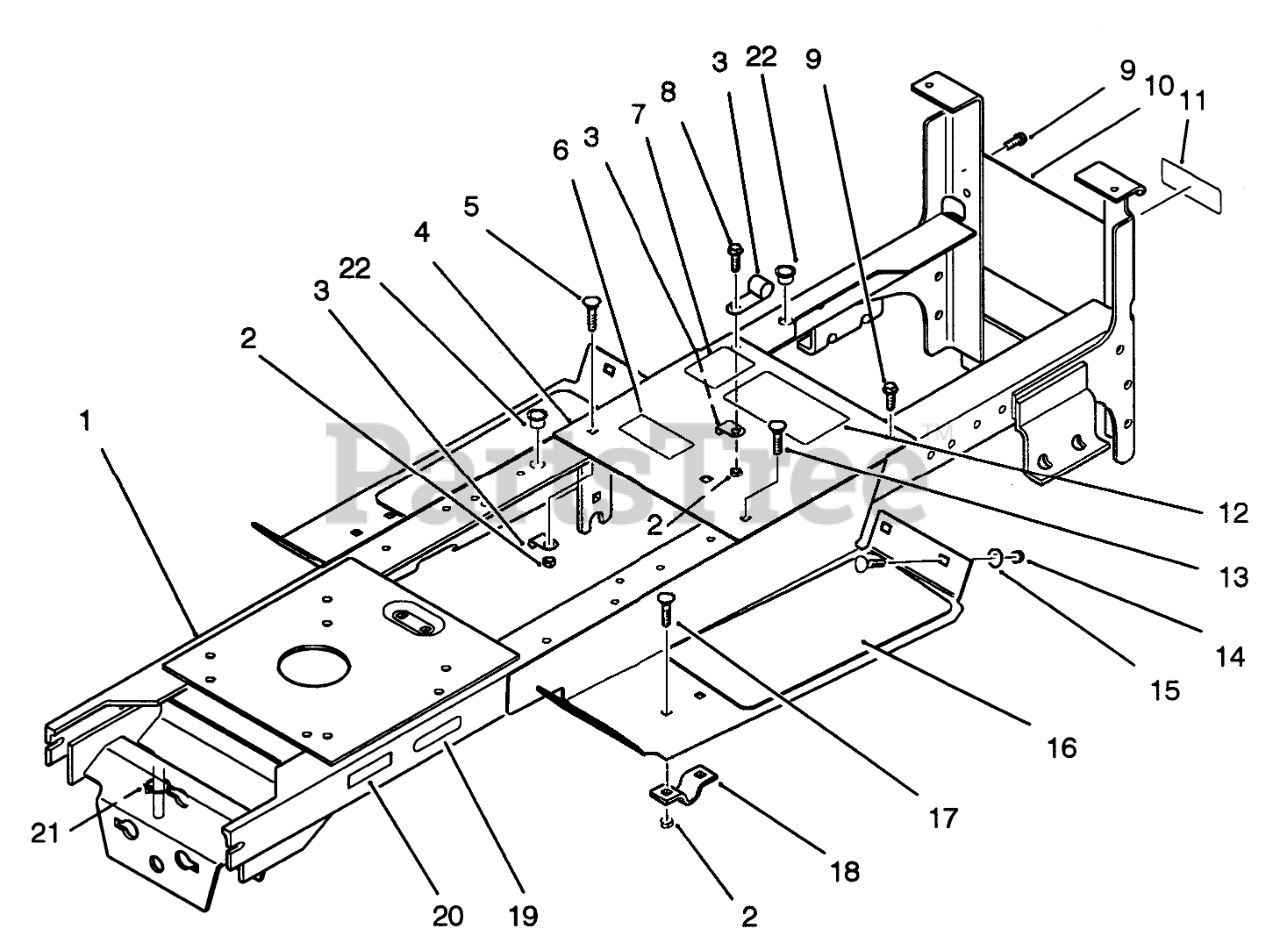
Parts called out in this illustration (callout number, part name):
1	Frame
2	NUT-LOCK, NI
3	THROTTLE CONTROL CLP
4	Panel
5	Bolt-Carriage
6	DECAL-DANGER
7	DECAL-PARKING BRAKE
8	Bolt
9	Screw
10	PANEL-REAR R
11	DECAL-DANGER
12	DECAL-DANGER
13	SCREW-CARR
14	NUT-HEX
15	WASHER - FLAT YZ
16	PAD FOOTREST
17	NUT-HEX, JAM
18	CLAMP
19	DECAL - BELT INSTR.
20	Decal-Attac-O-Matic
21	PLASTIC TIE
22	BUSHING
